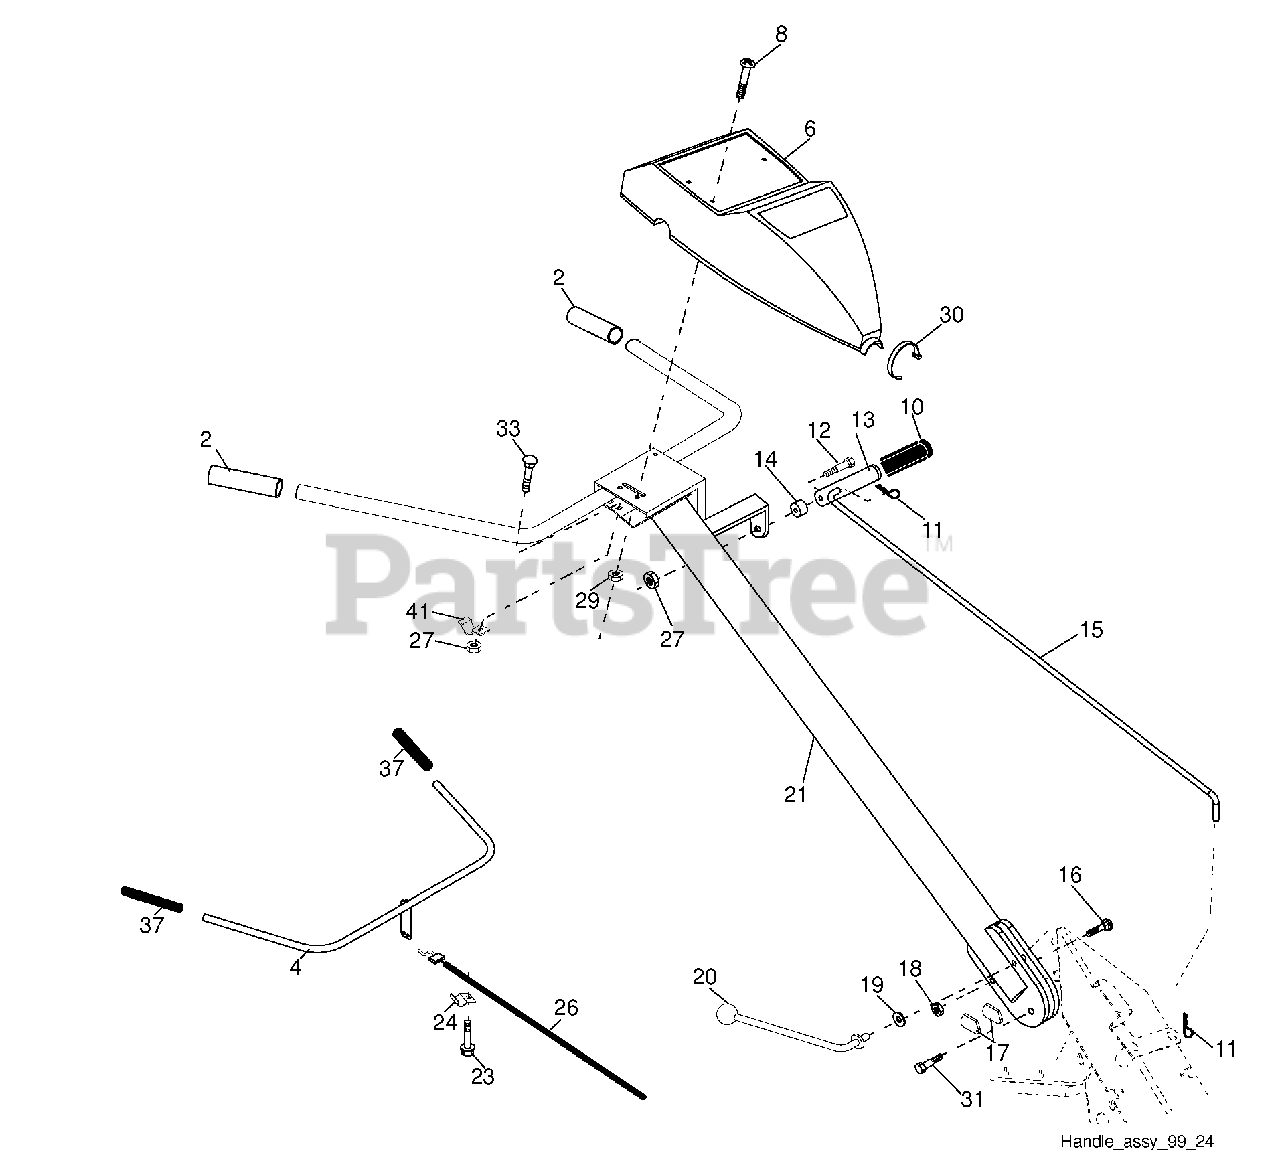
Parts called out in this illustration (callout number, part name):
2	Grip, Handle
4	Bar Assembly, Control
6	Panel, Control
8	Screw, Truss Hd. #10-24 unc x 1/2
10	Grip, Handle
11	Clip, Hairpin
12	Bolt, Shoulder
13	Handle, Shift
14	Grommet, Rubber
15	Rod, Shift
16	Bolt, Carriage 3/8-16 x 1 Gr. 5
17	Lock, Handle
18	Nut, Crownlock 3/8-16 unc
19	Washer 13/32 x 1 x 11 Ga.
20	Lever, Lock, Handle
21	Handle
23	Screw, Hex Washer SLT#10-24 x .50
26	Cable, Clutch
27	Nut, Hex Flange 1/4-20 unc
29	Nut, Keps #10-24 unc
30	Tie, Cable
31	Bolt, Pivot
33	Bolt, Carriage 1/4-20 unc x 1/2
37	Grip, Bar, Control
41	Clamp, Bar, Control
